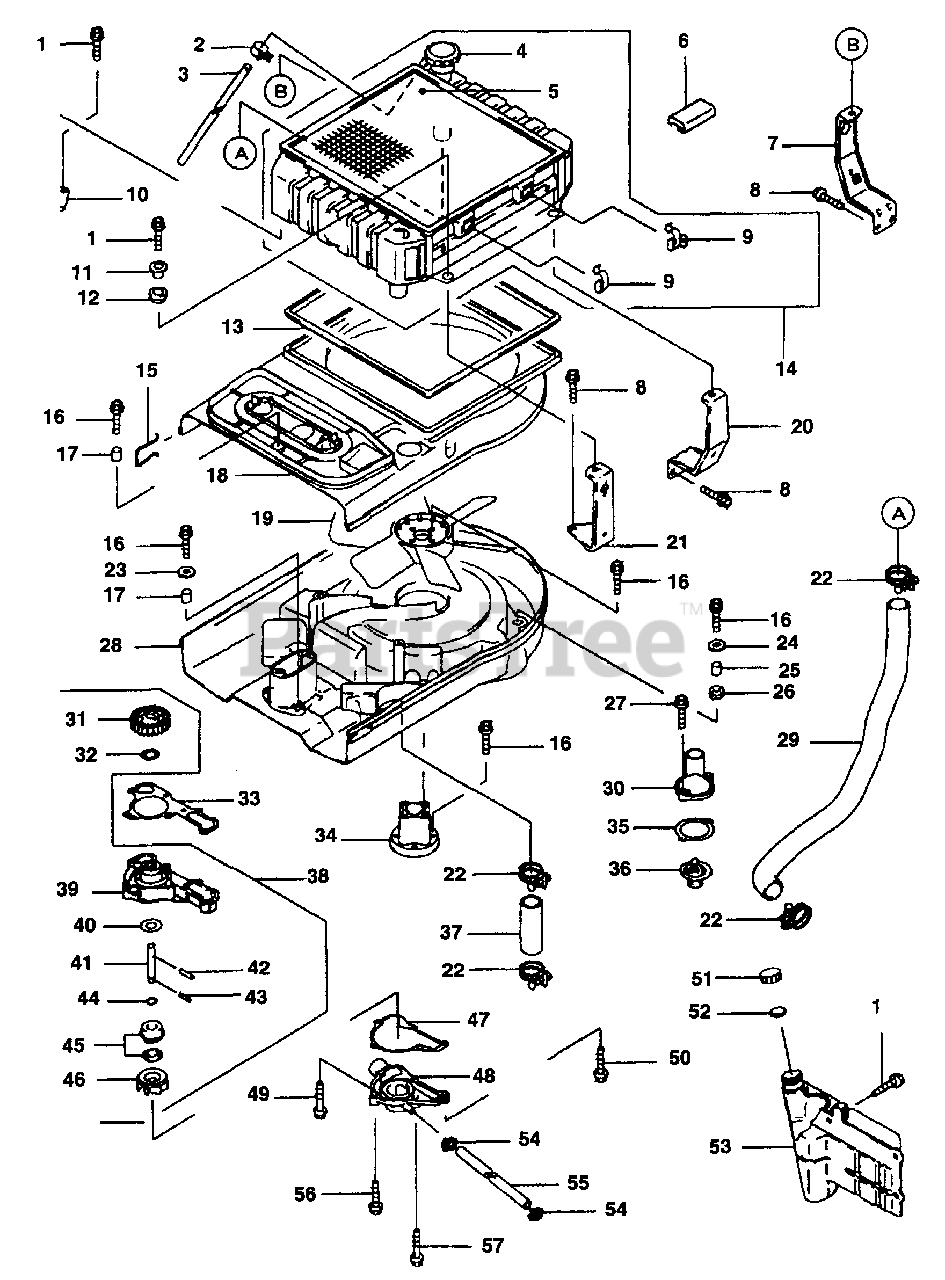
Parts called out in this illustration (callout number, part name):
1	Flanged Bolt
4	Pressure Cap Ass'y
7	Bracket
8	Flanged Bolt
14	Radiator Ass'y
16	Flanged Bolt
21	Bracket
33	Pump Case Gasket
35	Thermostat Cover Gasket
36	Thermostat
38	Water Pump
41	Impeller Shaft
45	Mechanical Seal
47	Pump Cover Gasket
48	Pump Cover
49	Flanged Bolt
50	Flanged Bolt
56	Flanged Bolt
57	Flanged Bolt
